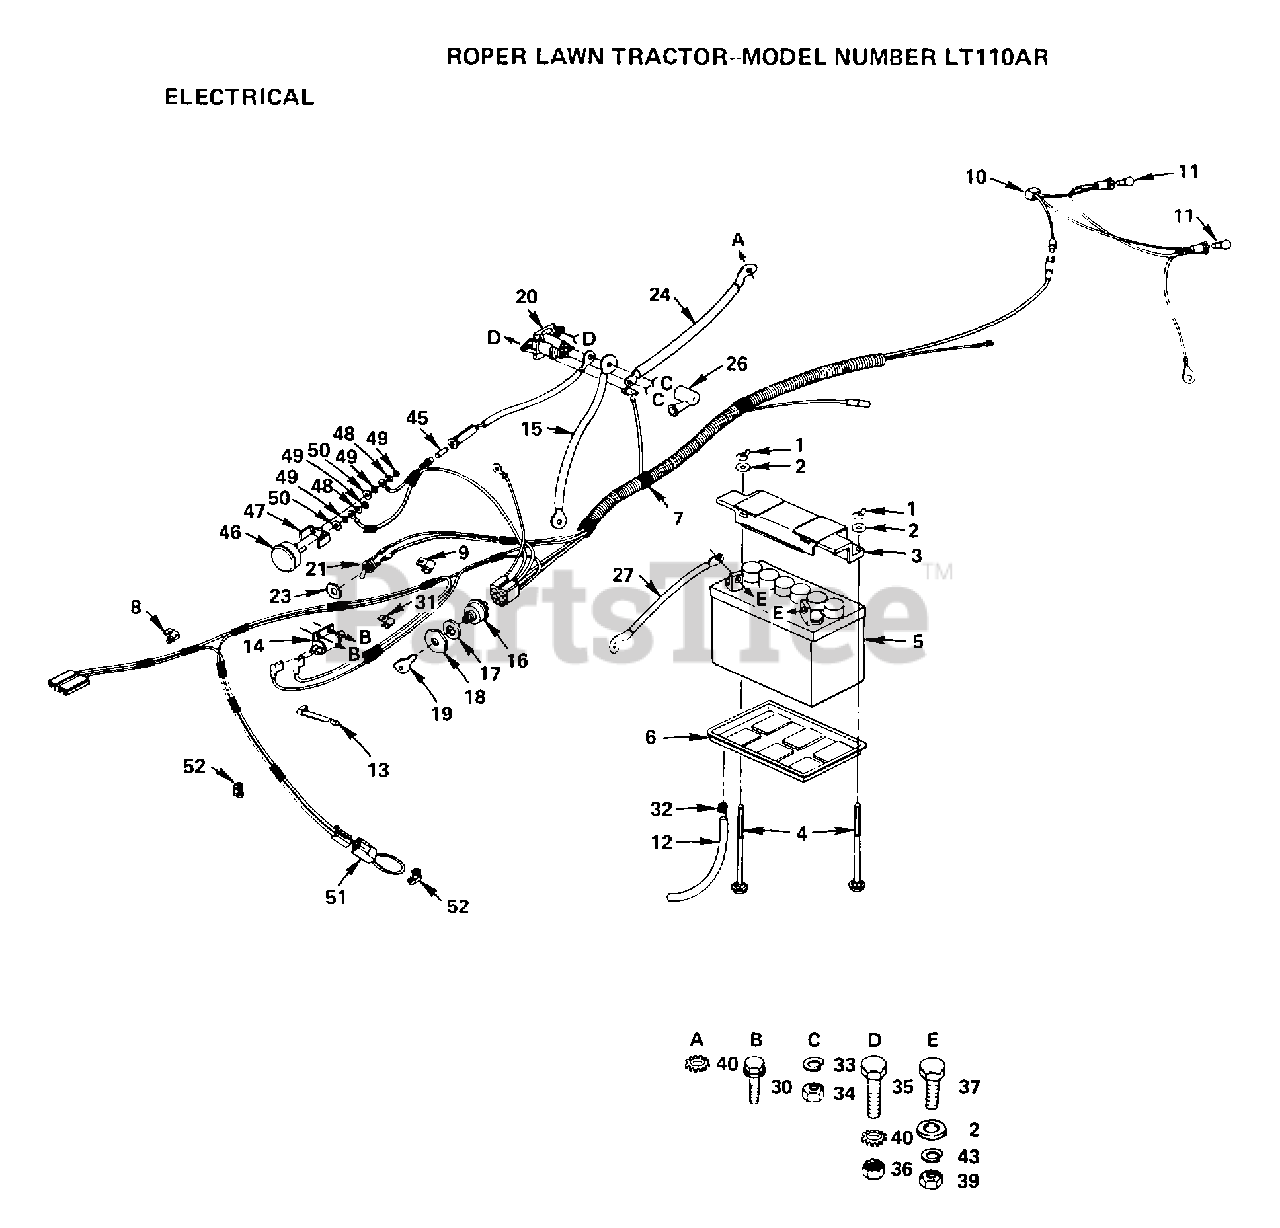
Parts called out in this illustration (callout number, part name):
2	WASHER
4	BOLT
6	"TRAY T, BATTERY"
8	CLIP GTV
10	HARNESS T
13	WIRE TIE
15	"CABLE T, BATTERY"
17	LOCKWASHER
18	CONDUIT NUT L
21	LIGHT SWITCH T
27	CABLE ASSY LT
31	CLIP T
34	NUT
35	BOLT
36	NUT
37	BOLT LT
43	LOCKWASHER
45	FUSE-30 AMP
46	AMMETER T
52	CLIPT
